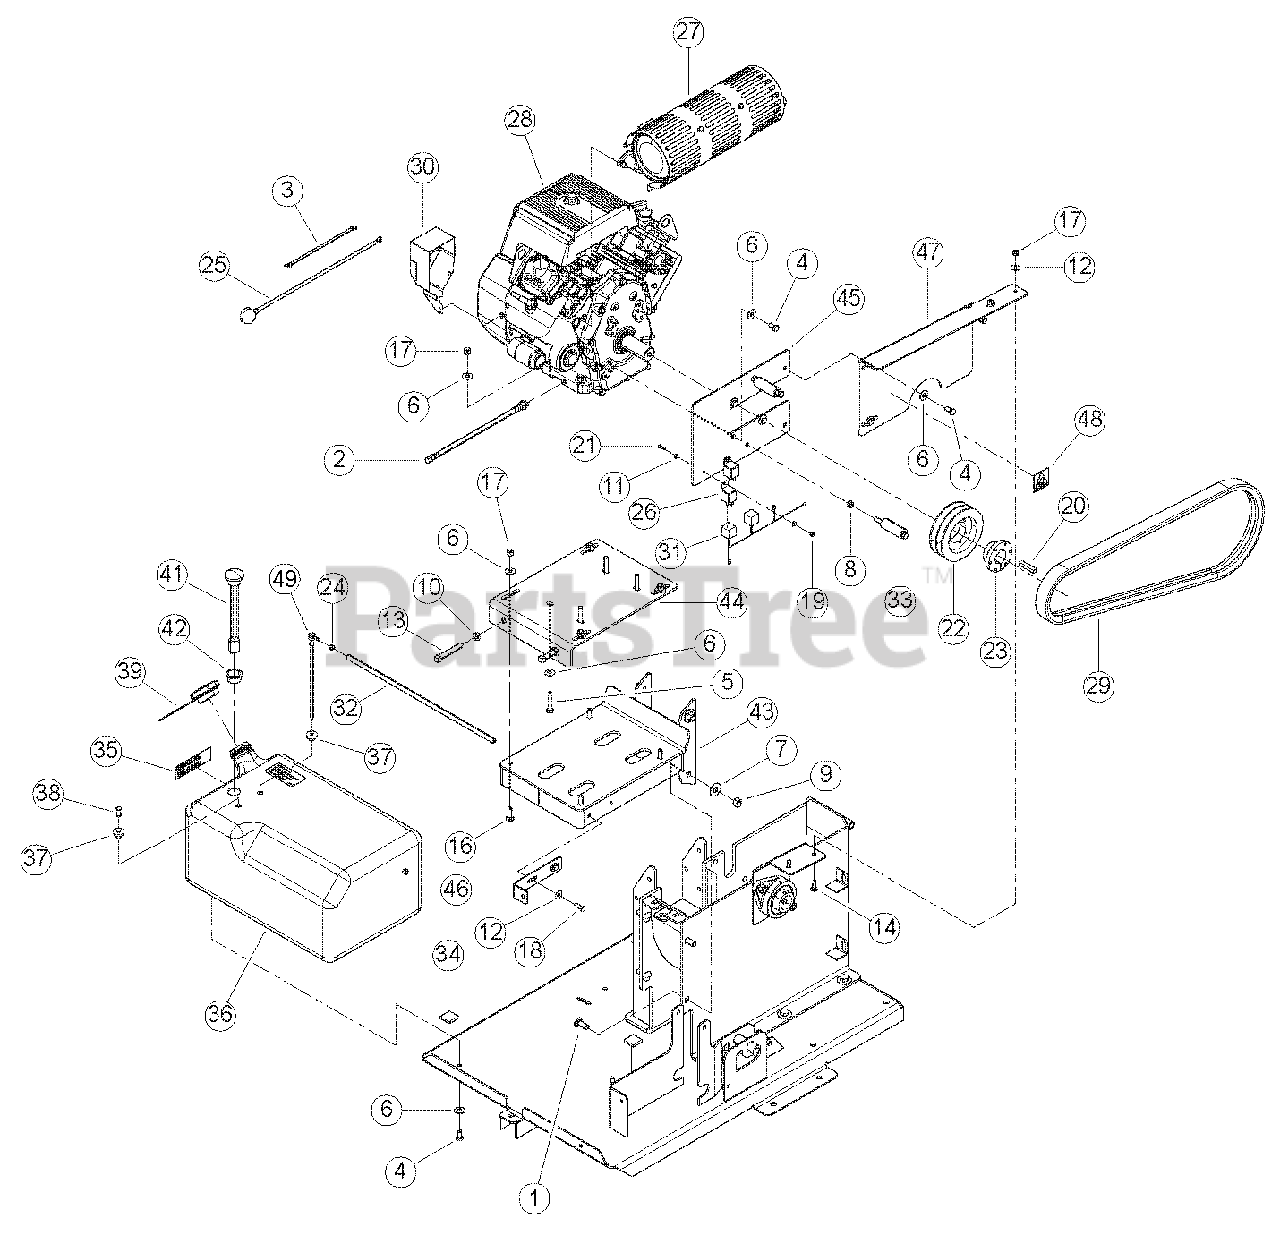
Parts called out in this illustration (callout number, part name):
1	BOLT, 1/2 X 1-1/4 CRG GR5 ZP
2	HOSE ASSY, CRANKCASE DRAIN
3	CABLE, 24" NEG (R / R)
4	BOLT, 3/8 X 3/4 HEX HD GR5 ZP
5	BOLT, 3/8 X 2 HEX HD GR5 ZP
6	WASHER, 3/8 FLAT ZP
7	WASHER, 1/2 FLAT ZP
8	NUT, 3/8 HEX HD NC ZP
9	NUT, 1/2 CENTERLOCK GRB ZP
10	NUT, 1/2 NC ZP JAM
11	WASHER, 3/16 FLAT ZP
12	WASHER, 5/16 FLAT ZP
13	SETSCREW, 1/2 X 3 SQ HD 1/2 DOG PT
14	BOLT, 5/16 X 1 CRG
15	NUT, 5/16 NYLOCK
16	BOLT, 3/8 X 1-1/4 CRG GR5 NC ZP
17	NUT, 3/8 NE NYLOCK ZP
18	BOLT, 5/16 X 7/8 HHCS GR5 NC ZP
19	NUT, 10/24 NYLOCK TYPE NM, ZP
20	KEY, 3/8 SQUARE X 2 LONG PLAIN
21	MACHINE SCREW, #10-24 X 3/4 PAN HD PH ZP
22	SHEAVE, 2B 5.2 SDS
23	BUSHING, SDS 1-7/16"
24	CLAMP, 15/32" SPRING
25	CABLE, 33" POS (R / R WITH BOOT)
26	RELAY, 12V SPDT W/ FLANGE
27	MUFFLER, SUBARU V-TWIN (FOR SERVICE SEE ENGINE OWNER'S MANUAL OR YOUR NEAREST AUTHORIZED SUBARU ENGINE DEALER)
28	ENGINE, 653CC SUBARU EH65 (FOR SERVICE SEE ENGINE OWNER'S MANUAL OR YOUR NEAREST AUTHORIZED SUBARU ENGINE DEALER)
29	BELT, 2BRP67
30	CONTROL, SUBARU V-TWIN IGNITION
31	HARNESS, CARB SAFETY RELEAY
32	HOSE, 20" FUEL LINE
33	WELDMENT, BELT GUIDE
34	PAD, FOAM FUEL TANK DAMPER
35	DECAL, UNLEADED GASOLINE
36	TANK, 9.25 GAL. ROTOMOLDED FUEL
37	GROMMET, TANK FITTING
38	PLUG, TANK VENT
39	CAP, FUEL TANK VENTED
40	FITTING, TANK FUEL PICK-UP TUBE
42	GROMMET, KELCH 100 GAUGE
43	WELDMENT, ENGINE BASE
44	WELDMENT, ENGINE MOUNT PLATE
45	WELDMENT, BELT SHIELD BRACKET
46	WELDMENT, SHIELD BRACKET
47	ASSEMBLY, BELT GUIDE, SERVICE PART
48	DECAL, SHIELD DANGER ISO
